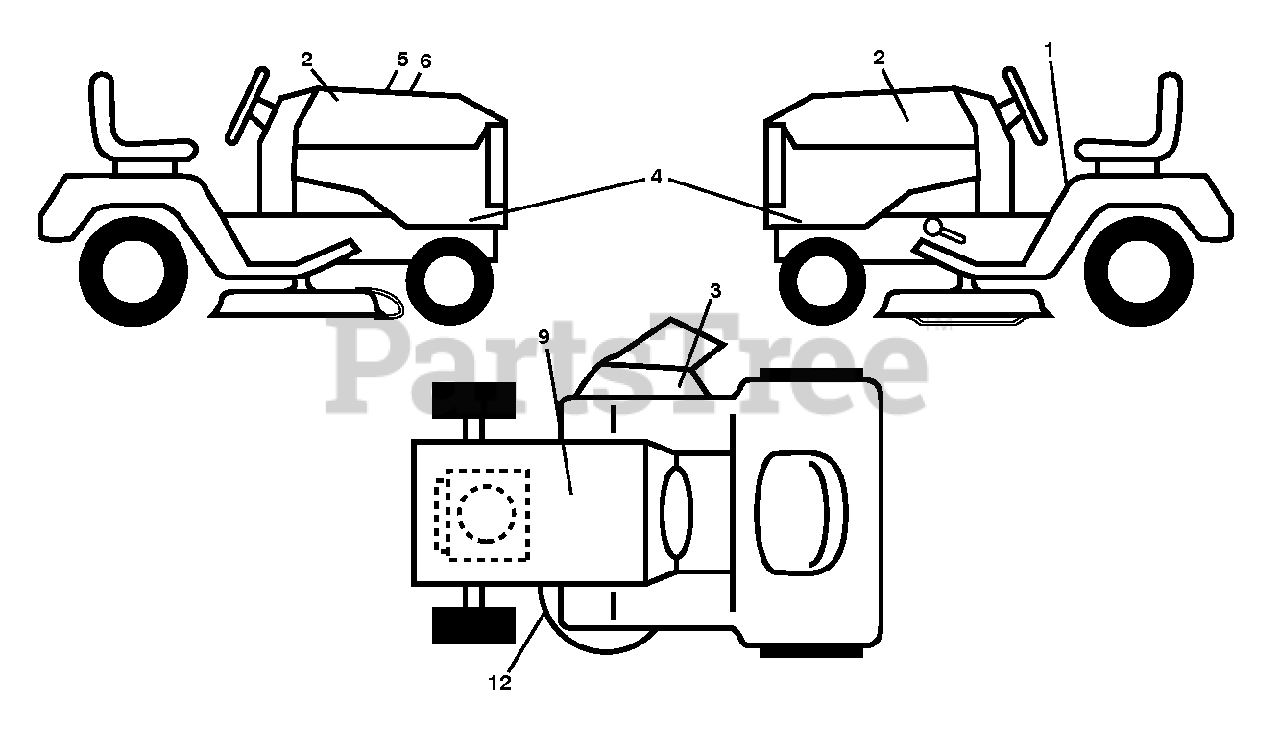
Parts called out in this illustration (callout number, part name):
1	DECAL.FENDER.WARNING.ENGLISH
2	DECAL.BADGE.170MM.TEXTLOGO.
3	DECAL.MOWER.WARN.KEEP.HAND.AWY
4	DECAL.SDPNL.GT2.YT46LS.SET
5	DECAL.WARNING.CUST.RESP.E85.
6	DECAL.RPL.KW651.TLW.REV46E.K46
9	DECAL BTRY SYMBOLS
12	DECAL.V-BELT.SCH.42/46"MEC/ELE
